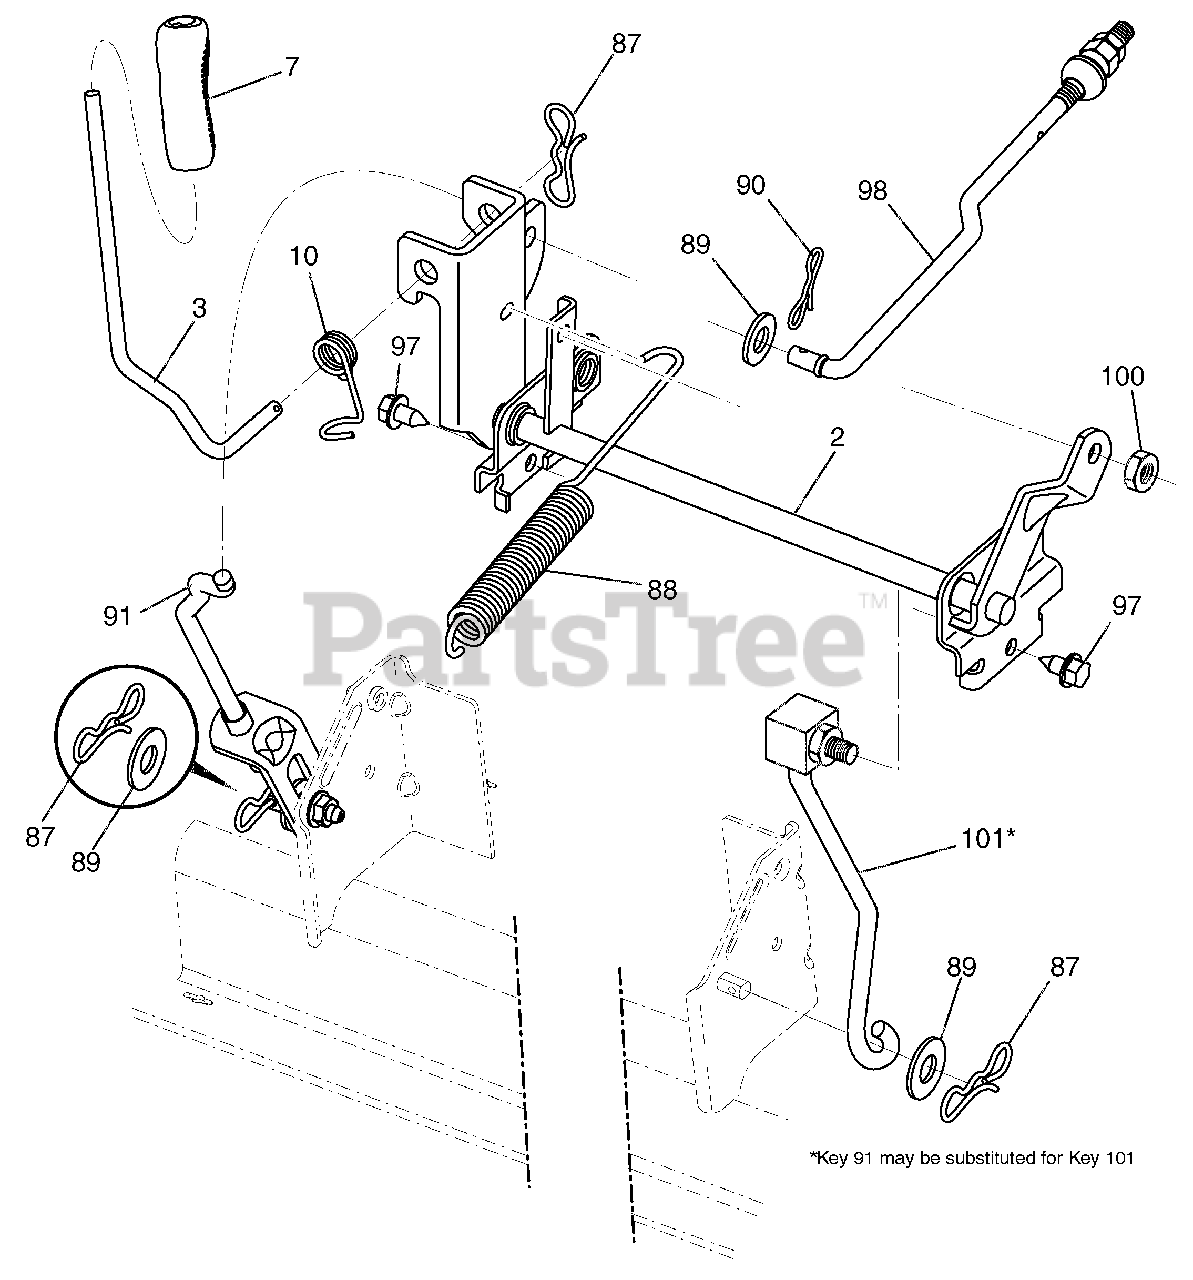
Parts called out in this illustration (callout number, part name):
2	SHAFT ASM., LIFT
3	LEVER.LIFT.HANDLE.LT
7	GRIP LEVER 5625 LD BLACK 428
10	SPRING.TORSION.HANDLE.LIFT
87	PIN.COTTER.7/16.BOW TIE LOCK
88	SPRING.LIFT ASSIST
89	WASHER.CLEAR ZINC
90	PIN.COTTER.5/16.BOW TIE LOCK
91	LINK.LIFT.SUSP.MOWER.REAR
97	SCREW.HEXWSH THDR3/8-16X3/4.BL
98	LINK.LIFT.SUSP.FRONT
100	NUT.CENTERLOCK.3/8-16 UNC.
101	LINK ASM
